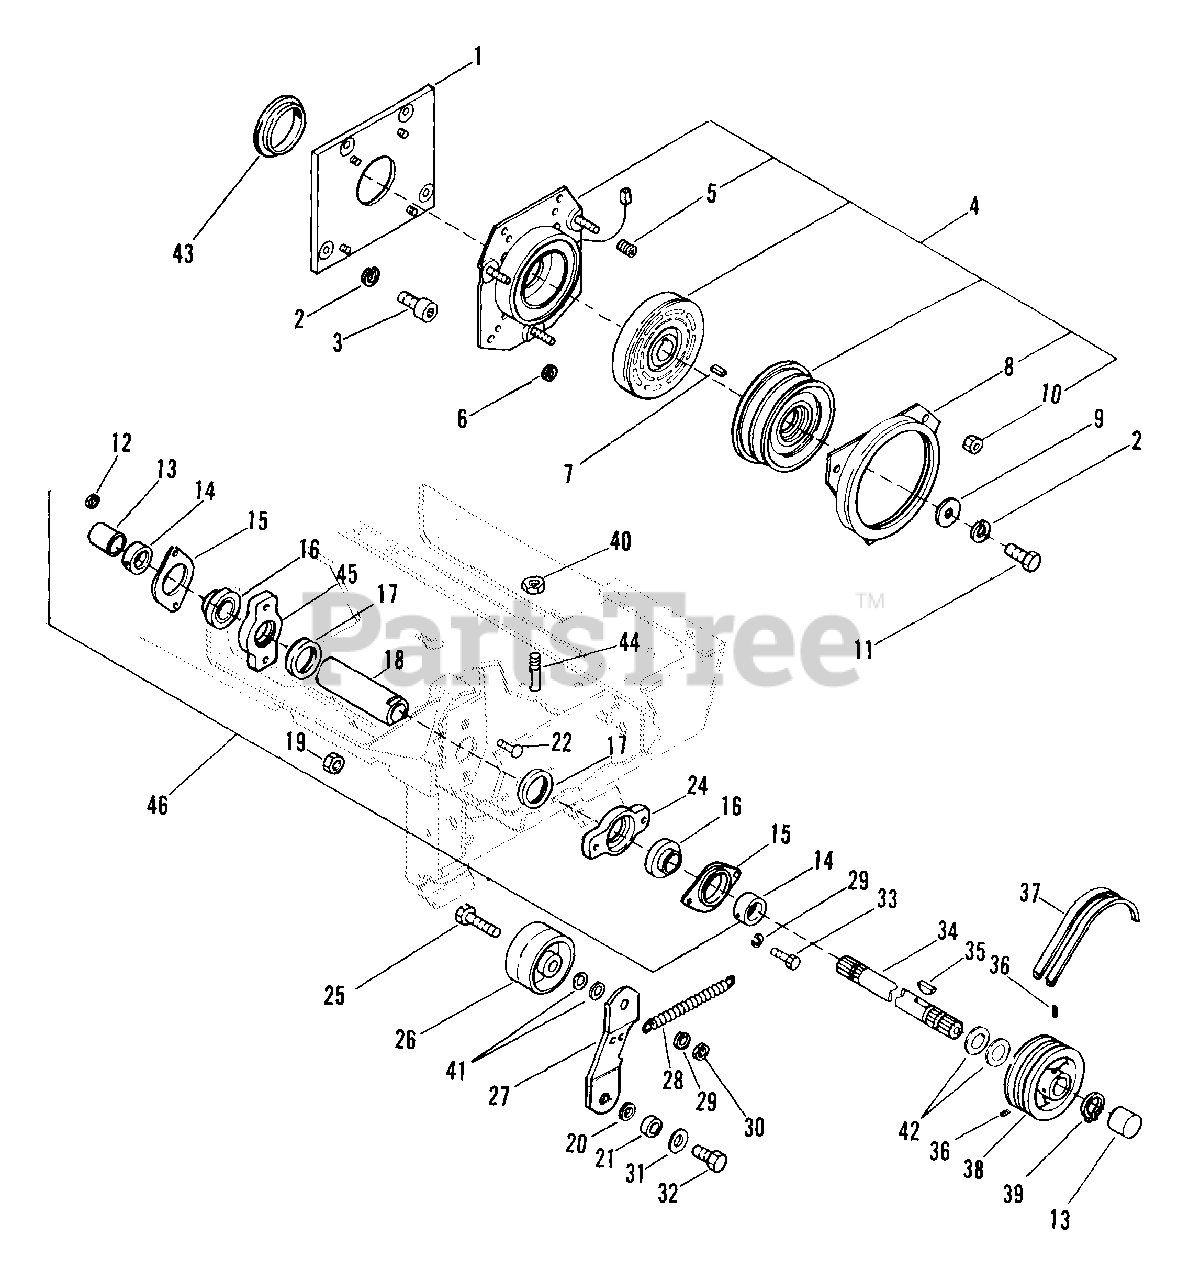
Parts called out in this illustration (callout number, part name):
1	CLUTCH ADAPTER WELD'T
2	WSHR-LK .438X.133 HVY
3	SCR-SKH .44-14X.75 GR 2 PL
3	BRG-BALL 1.57X3.15X.71
4	DIESEL CLUTCH ASSEMBLY
4	CLUTCH ASSEMBLY 1 1/8 BORE
4	CLUTCH ASSEMBLY 1-1/4 BORE
5	SG-COMP WARNER ELEC.
6	NUT-LK-CTR .375-16 GR A PL
7	KEY-SQ .25X.625X.25 SAE 8630
8	BRAKE DRUM
9	WSHR-FL-STL .515X1.625X.250
9	WSHR-FL-STL .718X1.375X.250
10	NUT-LK WARNER
11	BLT-HEX .44-20X1.50 PL GR5
11	BLT-HEX M18 X 1.5X80 PL
12	NUT-LK-CTR .375-16 GR A PL
13	SHAFT COVER
14	BEARING COLLAR
16	BRG/W COLLAR 1.0 X 2.047 X.844
17	BSHG-SLV 1.500X1.750X.560
18	PTO TUBE
18	P T O TUBE
19	NUT-LK-CTR .50-13
20	SHIM SPACER
21	SPACER .512X.747X.208
22	BLT-RDHDSQNK .38-16X1.50 PL
23	ANTI PIVOT PLATE
24	BRG FLANGE
24	BEARING MOUNTING FLANGE
25	BLT-HEX .38-16X2.00 PL GR2
26	IDLER-FLAT 3.25 X .38 NWHAMSHR
27	IDLER ARM
28	SG-TENS .135X.98X6.0 WLD 62
29	WSHR-LK .375X.094 MED PL
30	NUT-HEX .375-16
31	WSHR-FL-STL .518X2.000X.105
32	BLT-HEX .50-13X1.25 PL GR2
33	BLT-HEX .38-16X1.50 PL GR2
34	FRONT PTO SHAFT
35	KEY-FTHR .25X1.25X.25 SAE
36	SCR-SET .32-18X.38 SKHCUPNL OH
37	V-BELT, 4L-WRAPPED (SET)
37	V-BELT, 4L-RAW EDGE (SET)
39	RG-RTNG-EXT 1.00X.042
40	NUT-LK-JAM-CTR .375-16 PL
41	WSHR-FL-STL .38X.875X.083 PL
42	WSHR-FL-STL 1.010X1.505X.062PL
43	PILOT BUSHING
44	LOCK STUD
45	BRG FLANGE
45	BEARING MOUNTING FLANGE
46	FRONT PTO ASSEMBLY
46	FRONT PTO KIT
